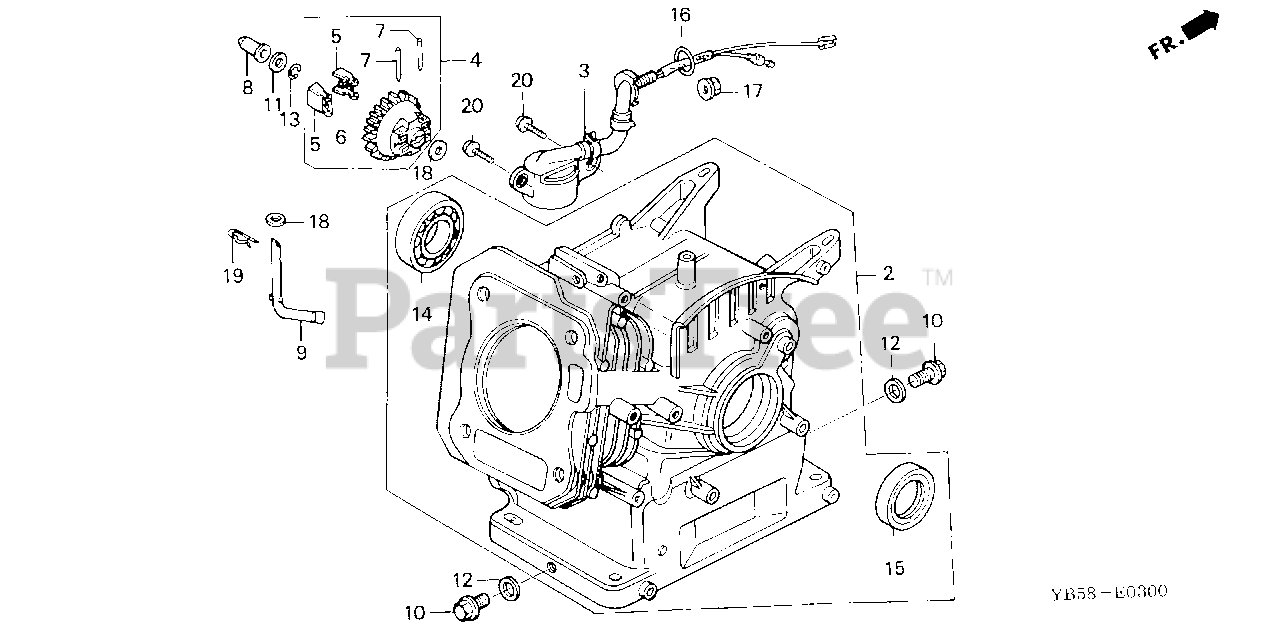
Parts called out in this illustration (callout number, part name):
2	CYLINDER ASSY. (OIL ALERT)
3	SWITCH ASSY., OIL LEVEL
4	GOVERNOR ASSY.
5	WEIGHT, GOVERNOR
6	HOLDER, GOVERNOR WEIGHT
7	PIN, GOVERNOR WEIGHT
8	SLIDER, GOVERNOR
9	SHAFT, GOVERNOR ARM
10	BOLT, DRAIN PLUG
11	WASHER, THRUST (6MM)
12	WASHER, DRAIN PLUG (10.2MM)
13	CLIP, GOVERNOR HOLDER
14	BEARING, RADIAL BALL (6205TMB) (NTN)
15	OIL SEAL (25X41X6)
16	O-RING (14MM) (ARAI)
16	O-RING (14MM) (NOK)
17	NUT, FLANGE (10MM)
18	WASHER, PLAIN (6MM)
19	PIN, LOCK (8MM)
20	BOLT, FLANGE (6X12)
